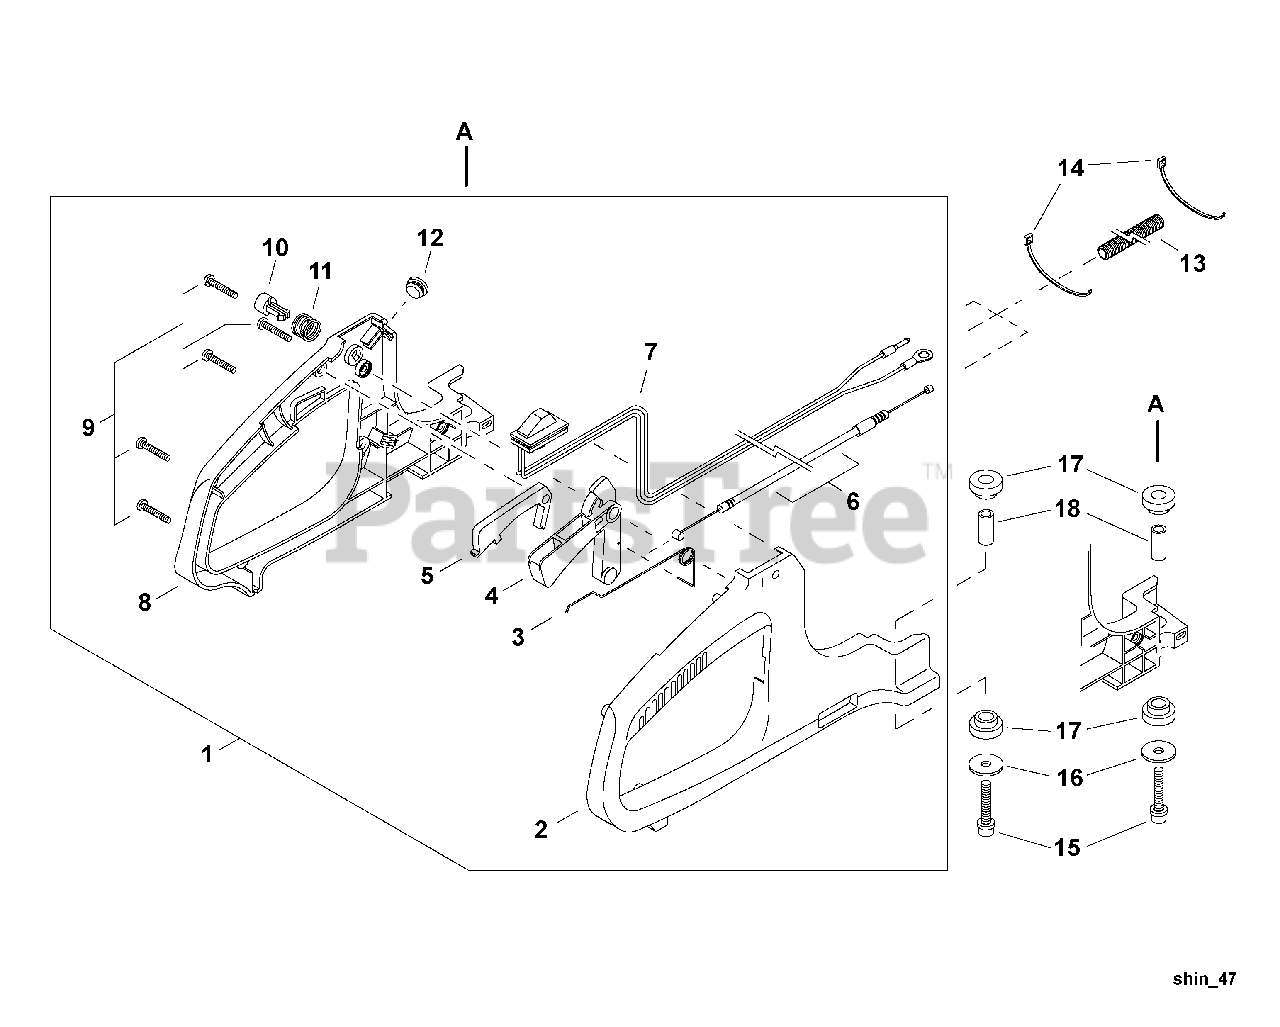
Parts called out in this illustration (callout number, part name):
1	HANDLE ASSY - REAR
2	RIGHT HANDLE BODY
3	SPRING, TRIGGER
4	TRIGGER, THROTTLE
5	LEVER, TRIGGER LOCKOUT
6	CABLE, THROTTLE
7	IGNITION SWITCH ASSY
8	HANDLE, REAR - LEFT
9	SCREW - 4X8 -- TAPPING
10	LOCK, THROTTLE
13	TUBE, PROTECTIVE - CORRUGATED
14	TIE, CABLE
15	SCREW - 6X35
17	CUSHION
18	COLLAR - 6
